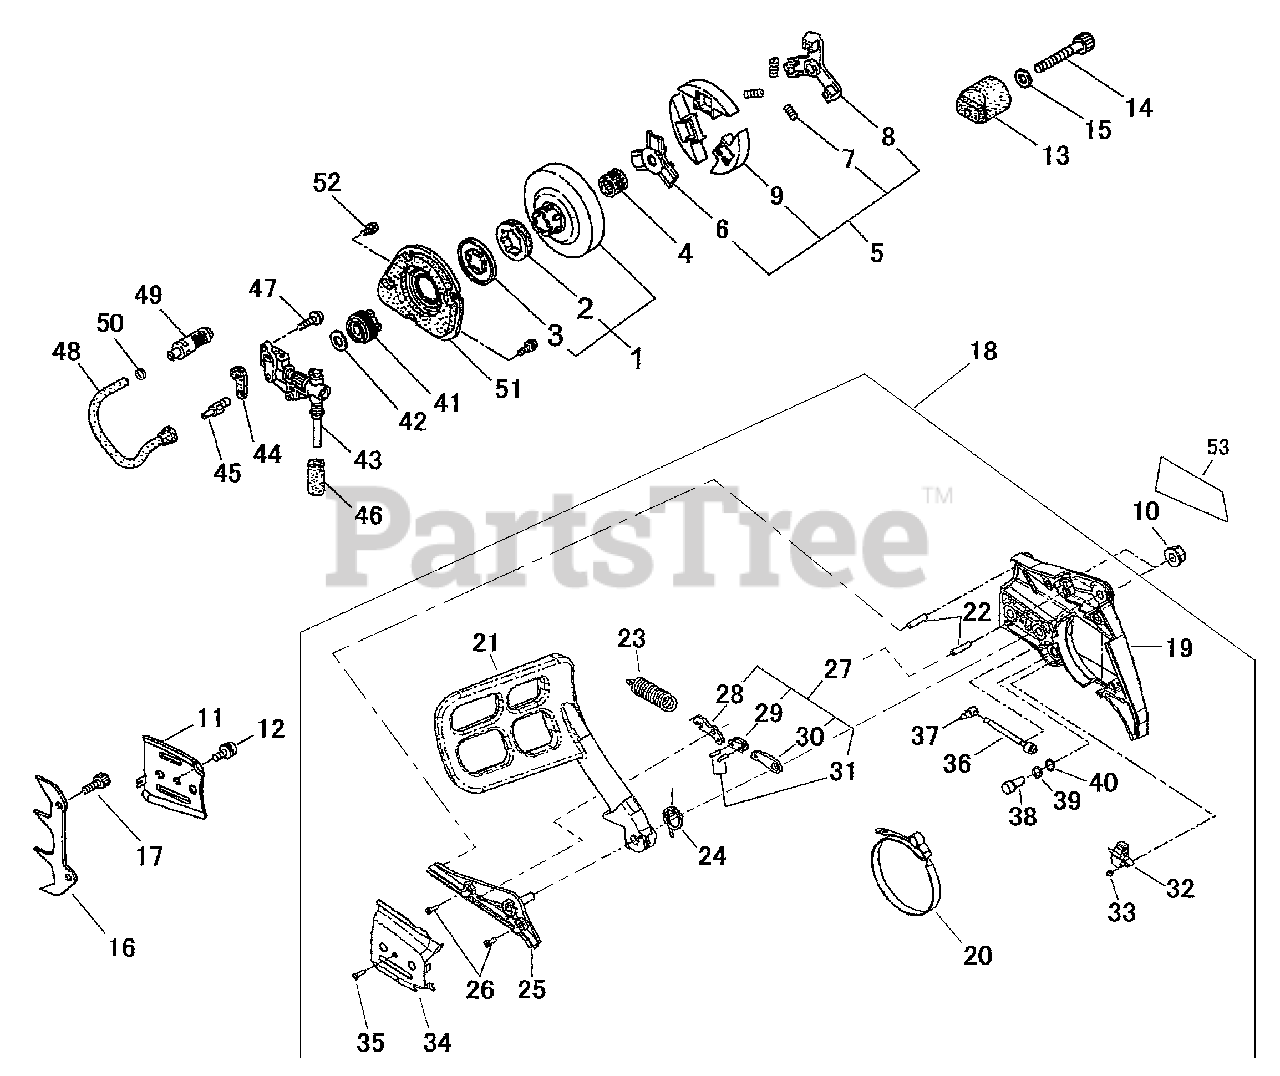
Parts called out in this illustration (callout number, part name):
1	CLUTCH ASSY
2	SPROCKET, RIM
3	COVER
4	BEARING, NEEDLE
5	CLUTCH ASSY
6	HUB, CLUTCH - INNER
7	SPRING, CLUTCH
8	HUB, CLUTCH - OUTER
9	SHOE, CLUTCH
10	NUT, GUIDE BAR
11	PLATE, GUIDE
12	SCREW - 4X7
13	CATCHER, CHAIN
14	BOLT - 5X25
15	WASHER - 5
16	SPIKE
17	BOLT
18	CLUTCH COVER ASSY
19	COVER, CLUTCH
20	BAND, BRAKE
21	LEVER
22	PIN - LOCATING
23	SPRING, CLUTCH
26	SCREW - 5X14 -- TAPPING
27	LEVEL ASSY
28	LEVER - INNER
29	TIE, CABLE
31	TIE, CABLE - 3X11.8
32	COVER
33	SCREW - 3X12 -- TAPPING
34	PLATE, GUIDE
35	SCREW -- TAPPING
36	SCREW
37	SLIDE PIN
38	GEAR
39	O-RING
40	WASHER
41	GEAR
42	WASHER, THRUST
43	AUTO-OILER ASSY
44	GASKET, PUMP
45	CONNECTOR
46	FILTER
47	SCREW - 4X16
48	PIPE - OIL
49	FILTER, OIL
50	CLIP
51	COVER
52	SCREW
53	LABEL - MODEL 490
